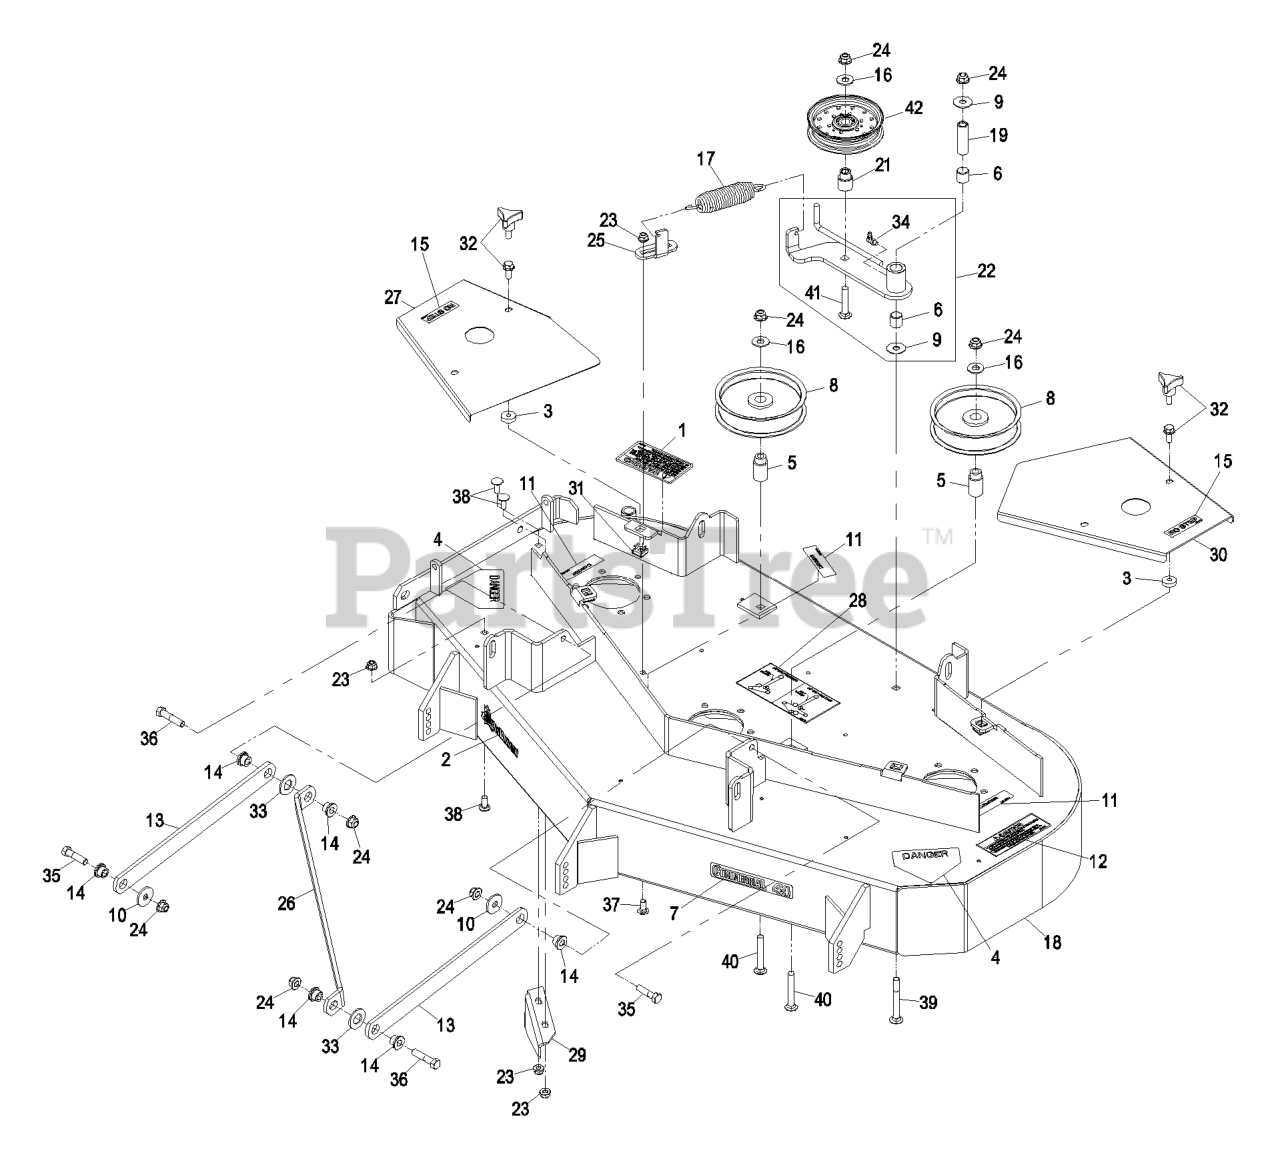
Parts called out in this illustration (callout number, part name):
1	DECAL-WARNING, DISCHARGE
4	DECAL-DANGER
5	BUSHING-IDLER
6	SLEEVE-BEARING
7	DECAL,COMMERCIAL 44
8	PULLEY-IDLER
11	DECAL-COVER, MISSING
12	DECAL,BOLT TORQUE
13	FLAT,STRUT
14	SPACER-STRUT
15	DECAL,NO STEP
16	WASHER-FLAT
19	BUSHING,IDLER ARM
20	ASM,DECK 44" COMPLETE
21	BUSHING,IDLER
22	ASM,IDLER PHAZER DECKS
23	NUT-HF, NI
24	NUT-HF, NI
25	ANCHOR,DECK SPRING
26	BRACE,DECK LINKAGE
27	COVER,BELT 44 RH
28	DECAL,BELT ROUTING 34/44
29	BAFFLE,DISCHARGE
30	COVER,BELT 44 LH
31	NUT,CAGE
32	SCREW-HHF
33	WASHER-FLAT
34	FITTING-GREASE, 90 DEG
35	SCREW-HH
36	SCREW-HH
37	BOLT-CARR
38	SCREW-CARR
39	SCREW-CARR
40	SCREW-CARR
41	SCREW-HH
